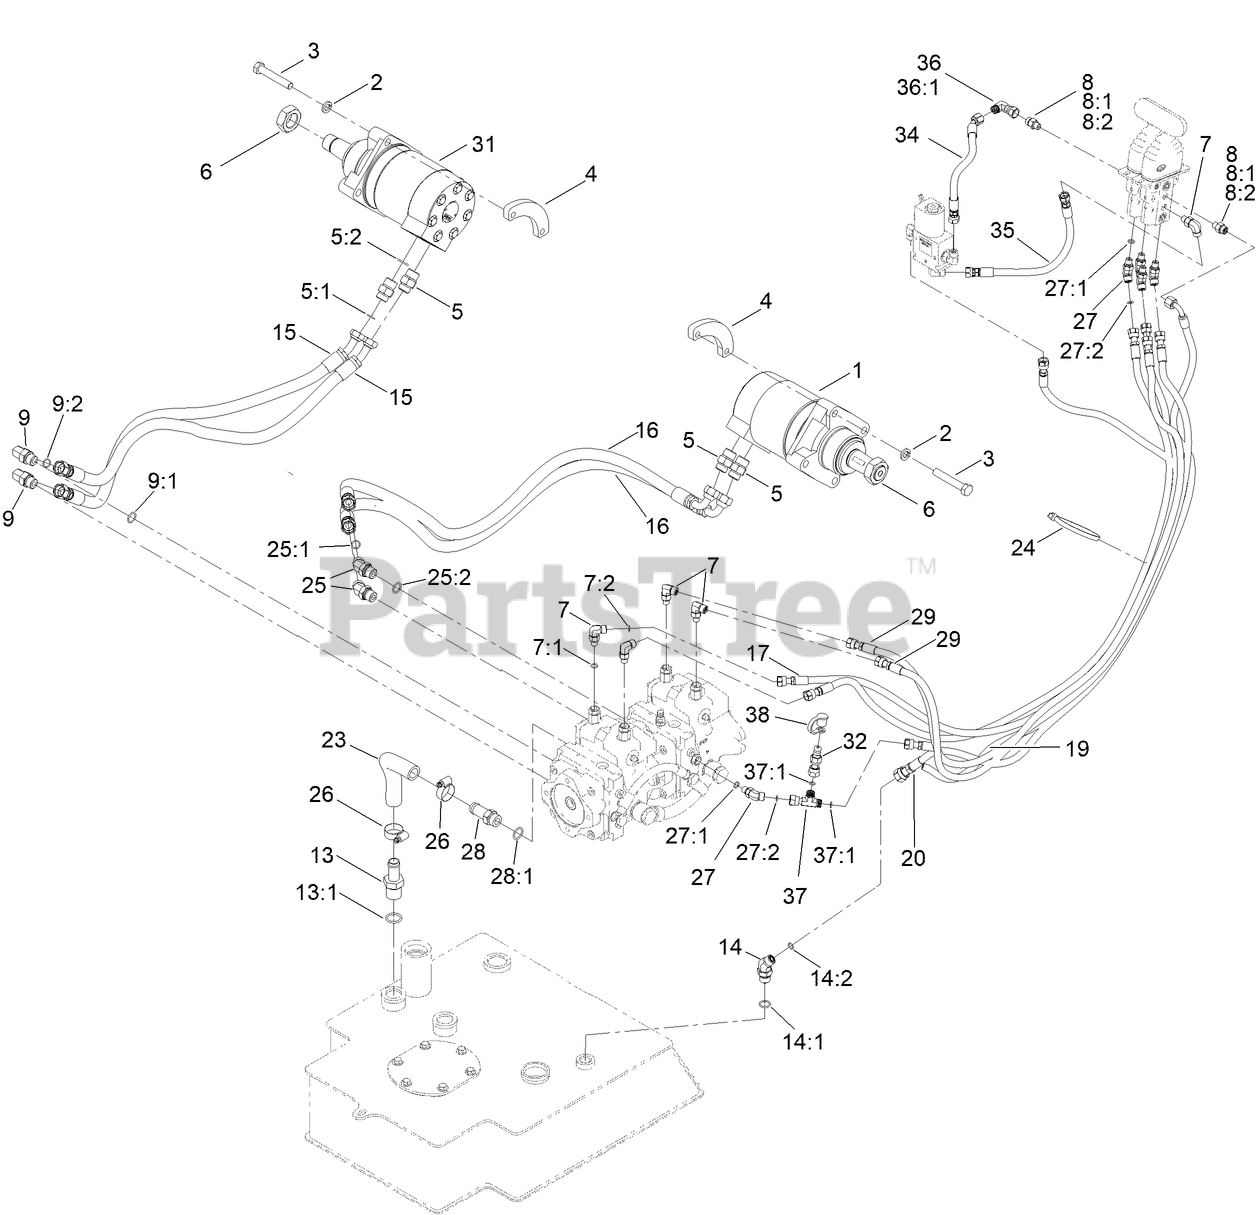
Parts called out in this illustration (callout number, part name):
1	MOTOR-HYD
2	WASHER-LOCK
3	SCREW-HH, TAP
4	PLATE-MOUNTING, WHEELMOTOR
5	FITTING-STRAIGHT
5:1	O-RING
5:2	O-RING
6	NUT-HEX
7	FITTING-ELBOW, 90 DEG
7:1	O-RING
7:2	O-RING
8	FITTING-STRAIGHT
8:1	O-RING
8:2	O-RING
9	FITTING-ELBOW, 90 DEG
9:1	O-RING
9:2	O-RING
13	FITTING
13:1	O-RING
14	FITTING-HYD, 45 DEG
14:1	O-RING
14:2	O-RING
15	HOSE-HYD
16	HOSE-HYD
17	HYD HOSE ASM
19	HYD HOSE ASM
20	HYD HOSE ASM
23	HOSE-RETURN
24	TIE-CABLE
25	FITTING-HYD, 45 DEG
25:1	O-RING
25:2	O-RING
26	CLAMP-HOSE
27	FITTING-HYD, 45 DEG
27:1	O-RING
27:2	O-RING
28	FITTING-STR
28:1	O-RING
29	HYD HOSE ASM
31	MOTOR-HYD
32	NIPPLE-TEST
34	HOSE ASM
35	HOSE ASM
36	FITTING-ADAPTOR
36:1	O-RING
37	FITTING-HYD
37:1	O-RING
38	CAP-DUST
